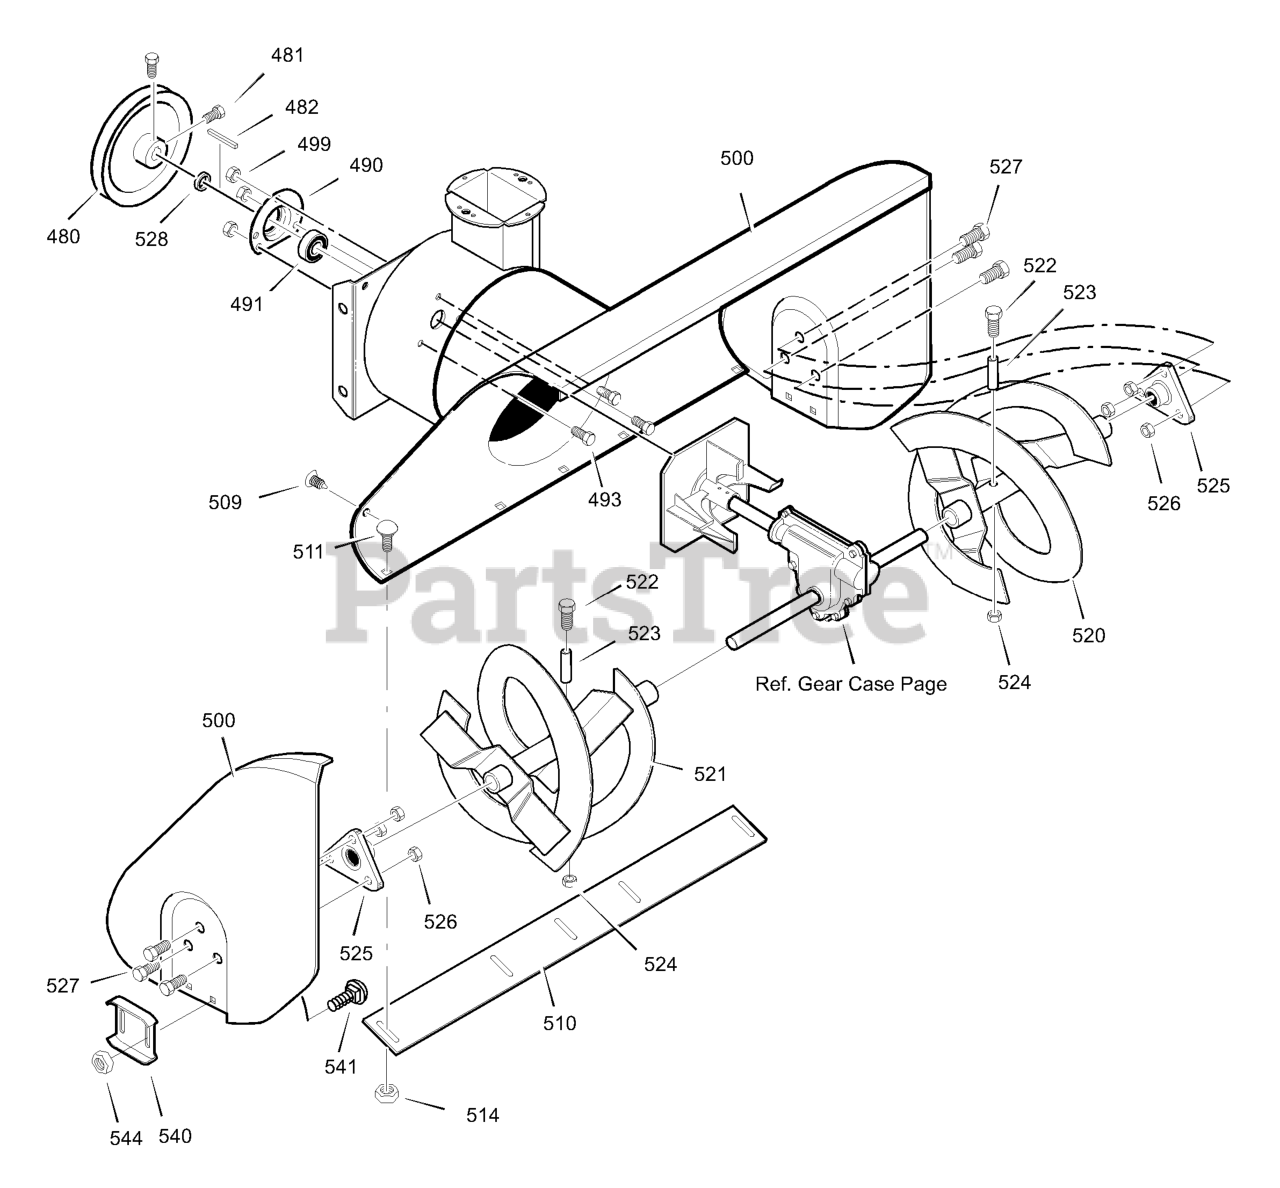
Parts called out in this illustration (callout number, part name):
480	PULLEY, 4L 6.12X .67
481	SCREW, 5/16-18 x 0.63
482	KEY, SQUARE 3/16 X 3/4
485	SPACER, FRICTION PULLEY
490	RETAINER, BALL BRNG
491	BEARING, BALL
493	BOLT, HEX 5/16-18X .50
499	NUT, 5/16-18 HEXWDFLLK
500	HOUSING, ASSY
509	FASTENER, RATCHET
510	BLADE, SCRAPER 24"
511	BOLT, 1/4-20X.75
514	NUT, 1/4-20
520	AUGER, ASSY, LH
521	AUGER, ASSY, RH
522	SCREW, 1/4-20X1.75
523	SPACER, SLEEVE
524	NUT, 1/4-20
525	BEARING,FLANGE
526	NUT, 5/16-18
527	SCREW, 5/16-18 x 0.75
540	SKID, HEIGHT ADJUST
541	BOLT, 5/16-18 X .75
544	NUT, 5/16-18
